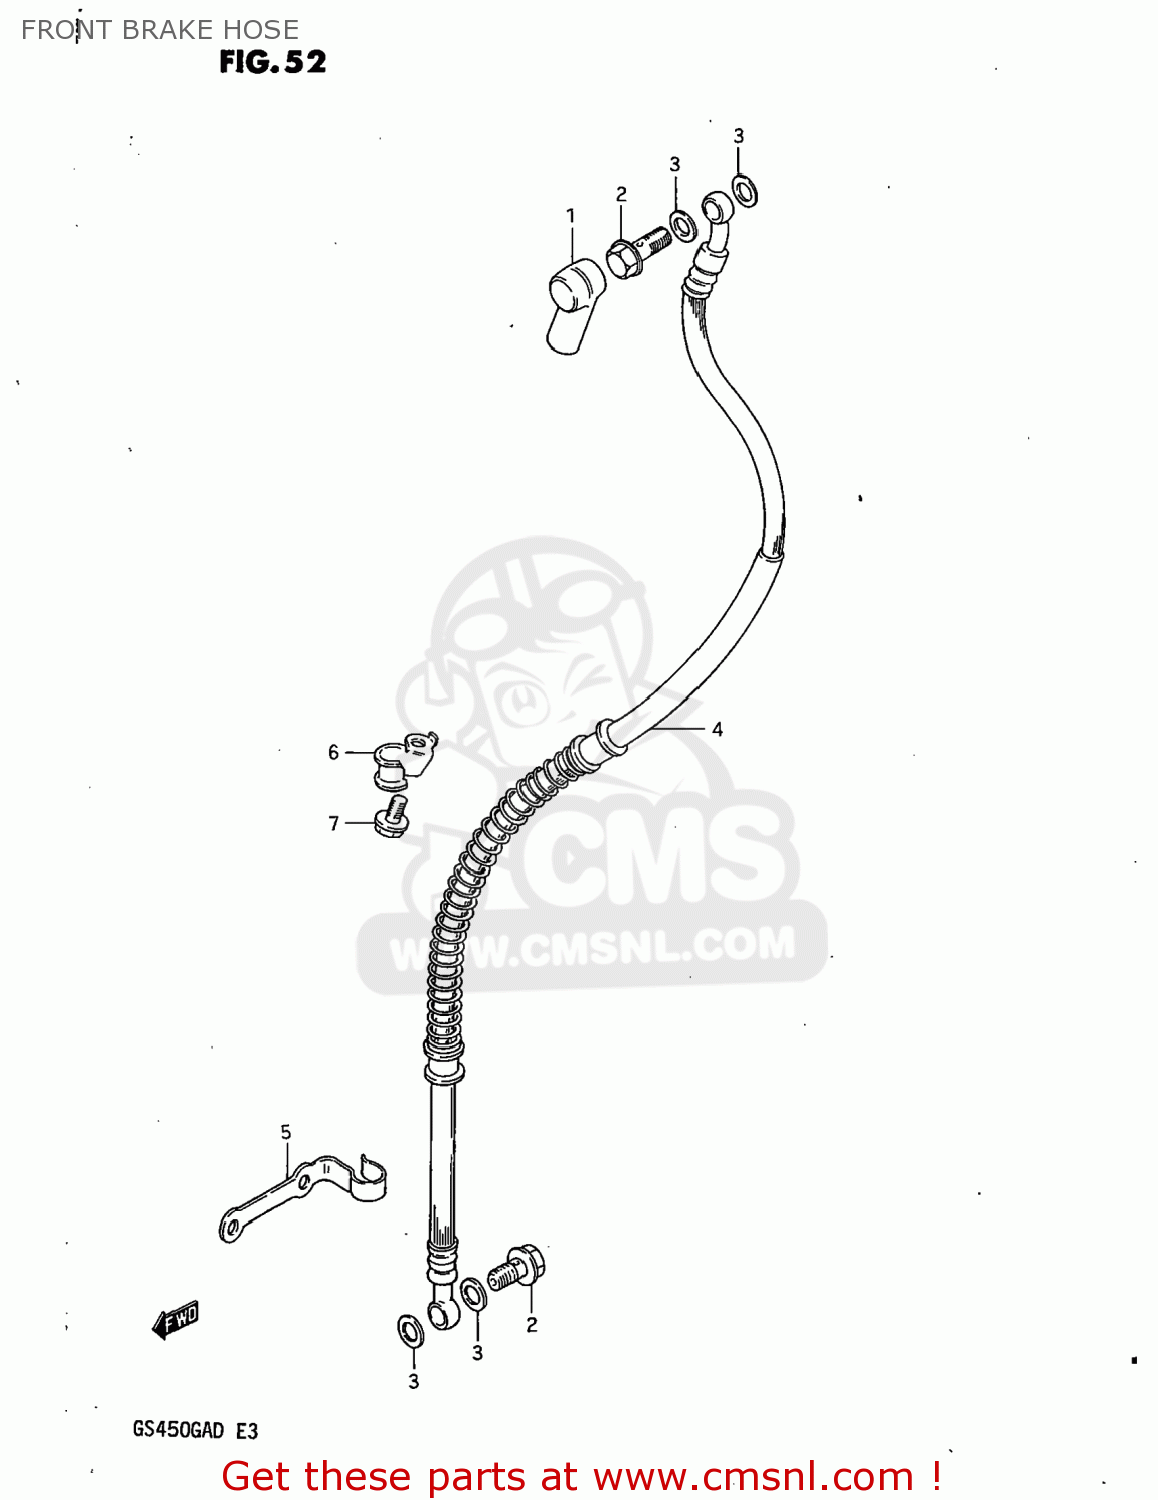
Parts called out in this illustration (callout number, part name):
1	BOOT,MASTER CYLINDER
2	BOLT,UNION
3	WASHER
4	HOSE,FRONT BRAKE
5	GUIDE,BRAKE HOSE NO.2
6	GUIDE,BRAKE HOSE NO.3
7	BOLT
